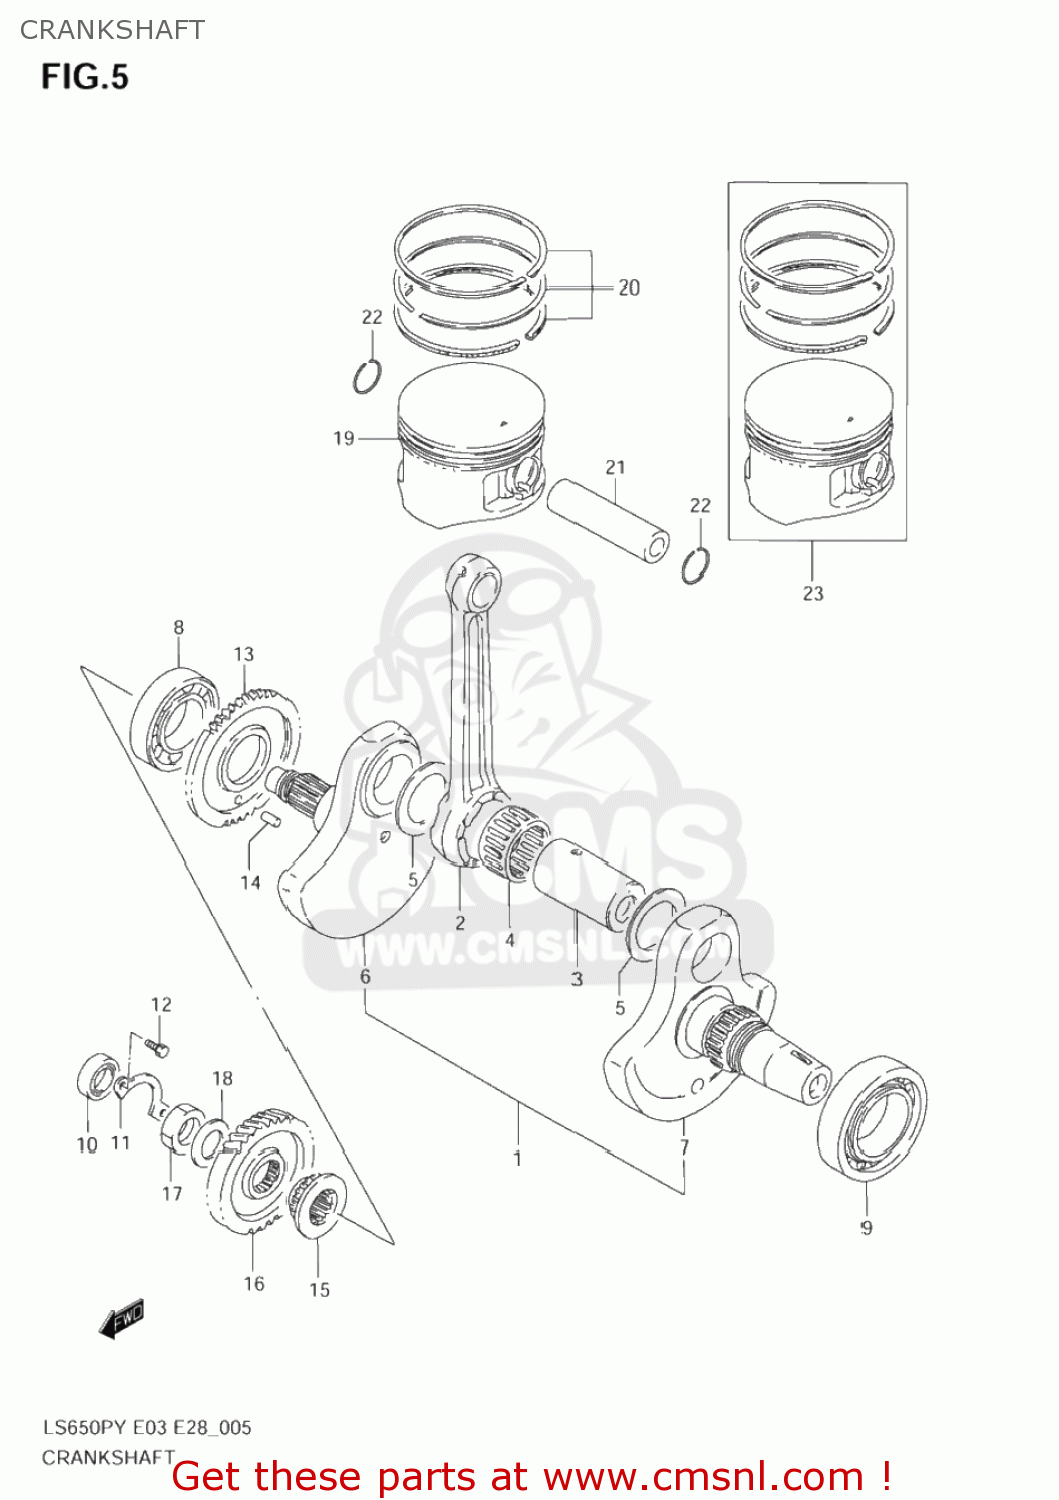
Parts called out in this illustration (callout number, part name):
1	CRANKSHAFT ASSY
2	ROD,CONNECTING
3	PIN,CRANK
4	BEARING(37X47X25)
5	WASHER(37X55X1)
6	CRANKSHAFT,R
7	CRANKSHAFT,L
8	BEARING(35X72X17)
9	BEARING(40X80X18)
10	SEAL,OIL(16X30X6)
11	RETAINER,CRANKSHAFT OIL SEAL,R
12	BOLT
13	GEAR,CRANK BALANCER DRIVE
14	PIN
15	SPROCKET,CAM CHAIN DRIVE
16	GEAR,PRIMARY DRIVE
17	NUT (20MM)
18	WASHER
19	PISTON
20	RING SET,PISTON
21	PIN,PISTON
22	CIRCLIP
23	PISTON SET(OS:0.5)
